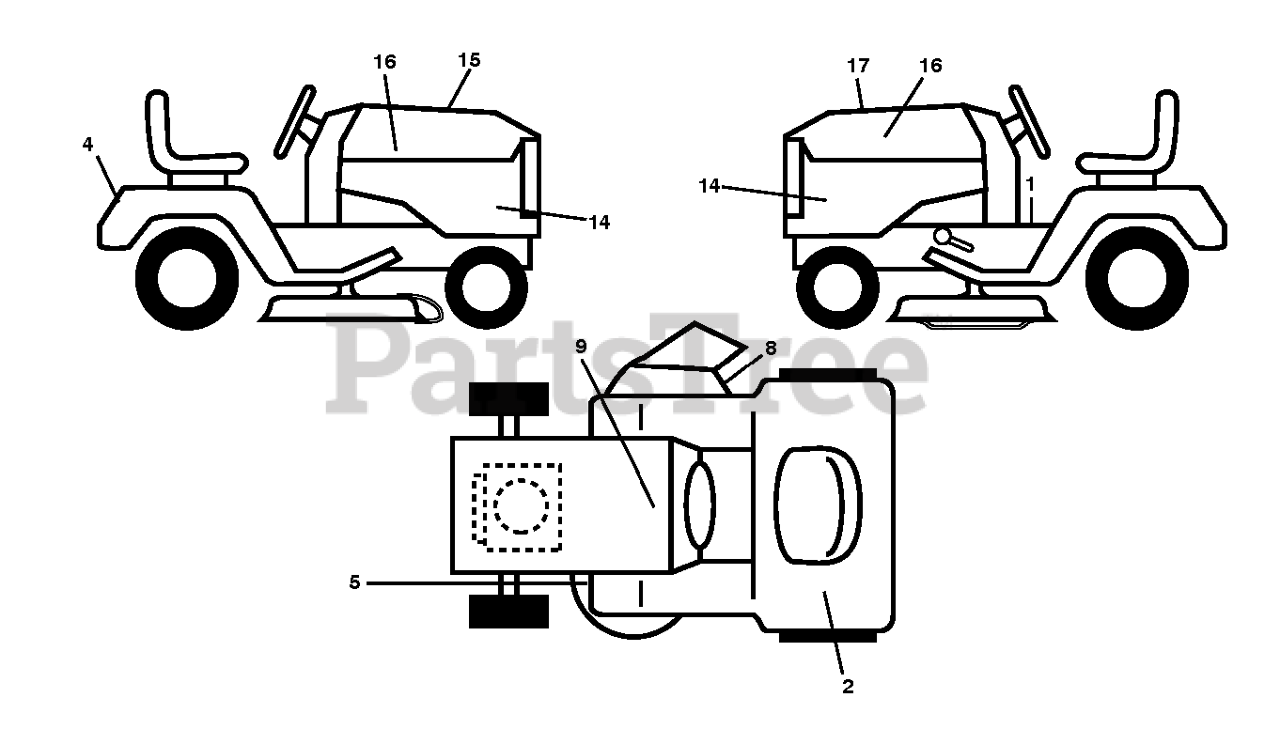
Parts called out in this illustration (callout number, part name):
1	DECAL.WARN.START.INSTRUCTIONS
2	DECAL,ETHANOL E85 WARNING
4	DECAL.FENDER
5	DECAL.MOWER
8	DECAL.MOWER.SCH.48/54
9	DECAL BTRY SYMBOLS
14	DECAL.PNL.SD.LGT2554.KOHL.
15	DECAL.WARNING.CUST.RESP.E85.
16	RP.DECAL.BADGE.170MM.TEXTLOGO
17	DECAL.RPL.KHSV730.TGW.54.0610F
